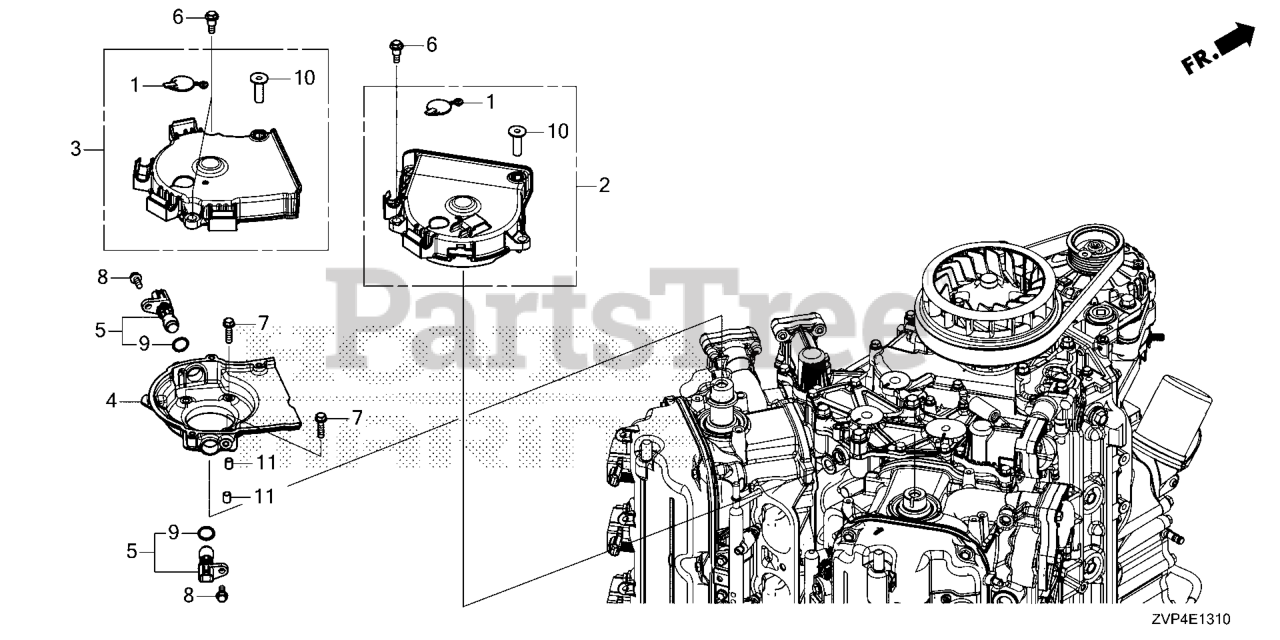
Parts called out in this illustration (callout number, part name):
1	GROMMET, TIMING BELT COVER
2	COVER ASSY., T/B R
3	COVER ASSY., T/B L
5	SENSOR ASSY., TDC
6	BOLT, T/B COVER
7	BOLT, FLANGE (6X25)
8	BOLT, FLANGE (6X16)
9	O-RING (15X1.9)
10	COLLAR, TIMING BELT COVER
11	PIN A, DOWEL (8X10)
